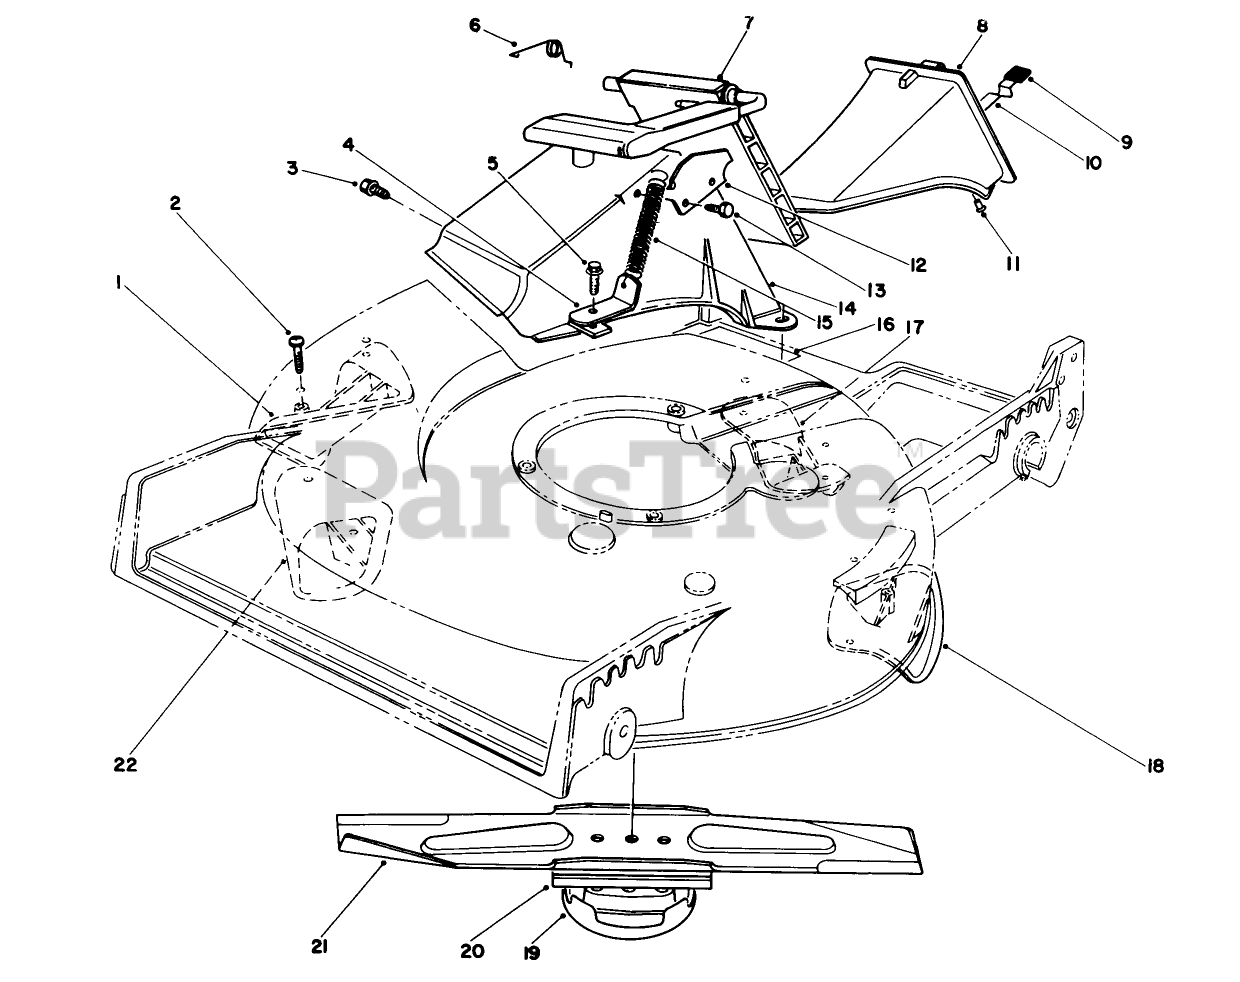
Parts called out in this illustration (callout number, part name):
1	KICKER
2	SCREW-PPH
3	SCREW AND WASHER ASM
4	Bracket-Spring
5	SCREW-HWH
6	RETAINER-DOOR
7	DOOR ASSEMBLY
8	Plug Assembly (Incl. Ref. #9-11)
9	GRIP-LATCH
10	LATCH-PLUG, DISCHARGE
11	RIVET-HEAD, FLAT
12	DOOR LATCH PLATE
13	SCREW-PLASTITE
14	DISCHARGE TUNNEL
15	SPRING-DOOR
16	DECAL
17	KICKER
18	KICKER
19	CUP-SCALP, ANTI
20	Stiffener
21	Blade Assembly (Incl. Ref. #20)
22	KICKER
